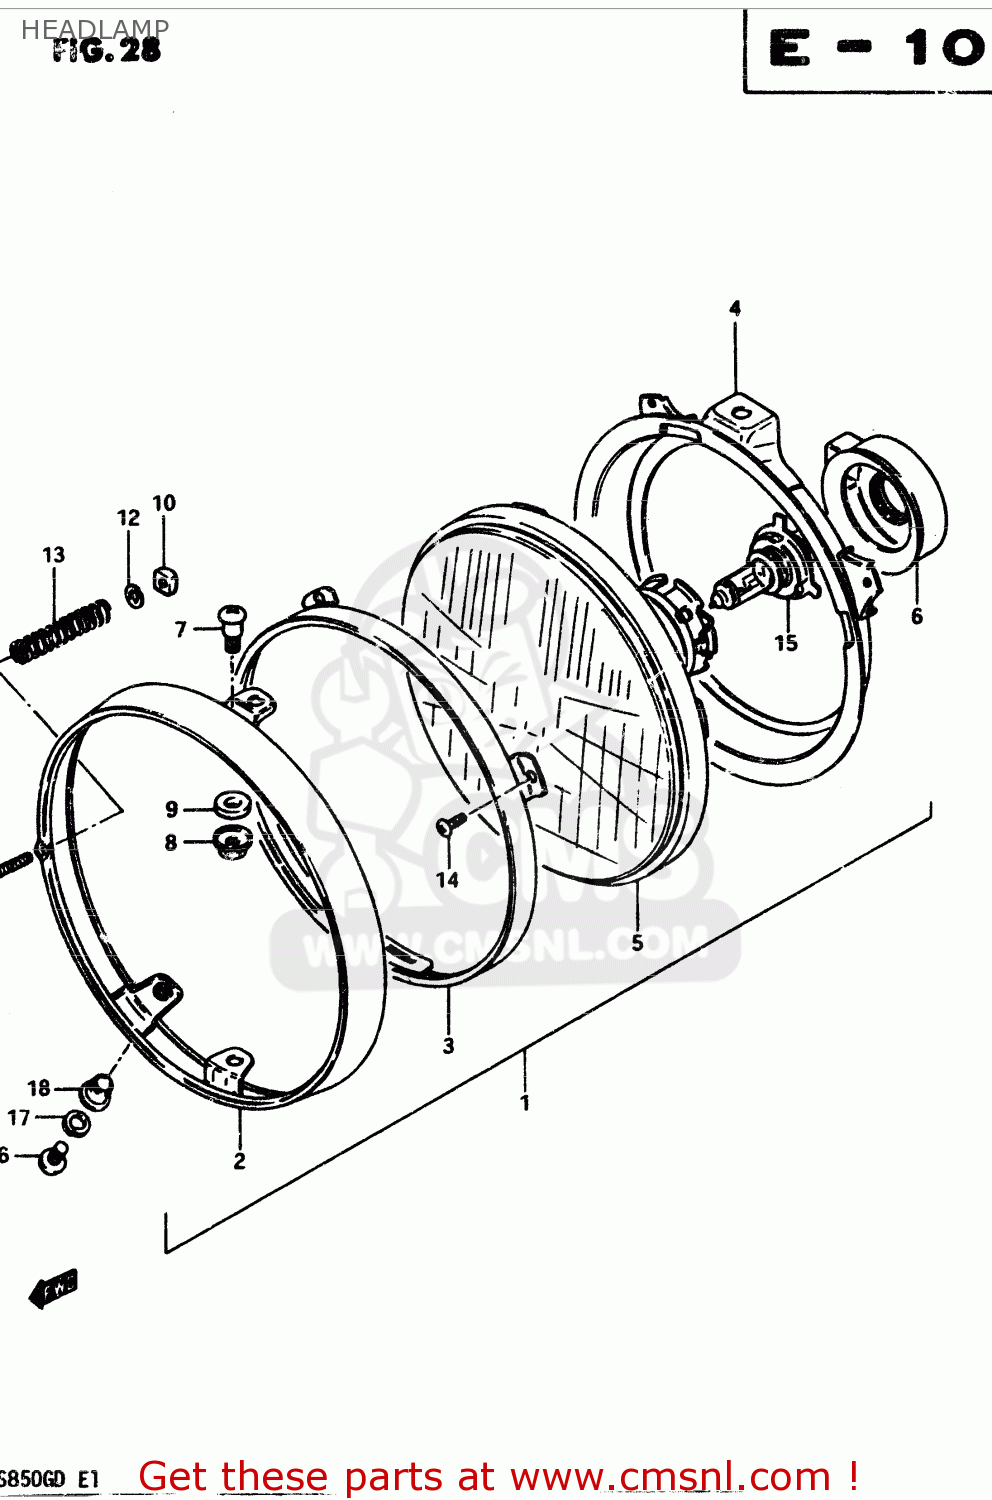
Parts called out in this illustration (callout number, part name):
1	HEADLAMP ASSEMBLY
2	RIM
3	RETAINER
4	RING,HEADLAMP UNIT
5	LAMP UNIT
6	COVER,HEADLAMP SOCKET
7	SCREW
8	NUT,ADJUSTING
9	SPACER
10	NUT
11	SCREW
12	WASHER
13	SPRING,HEADLAMP ADJUST
14	SCREW
15	BULB(12V60/55W,H4)
16	SCREW
17	WASHER,LOCK
18	WASHER
